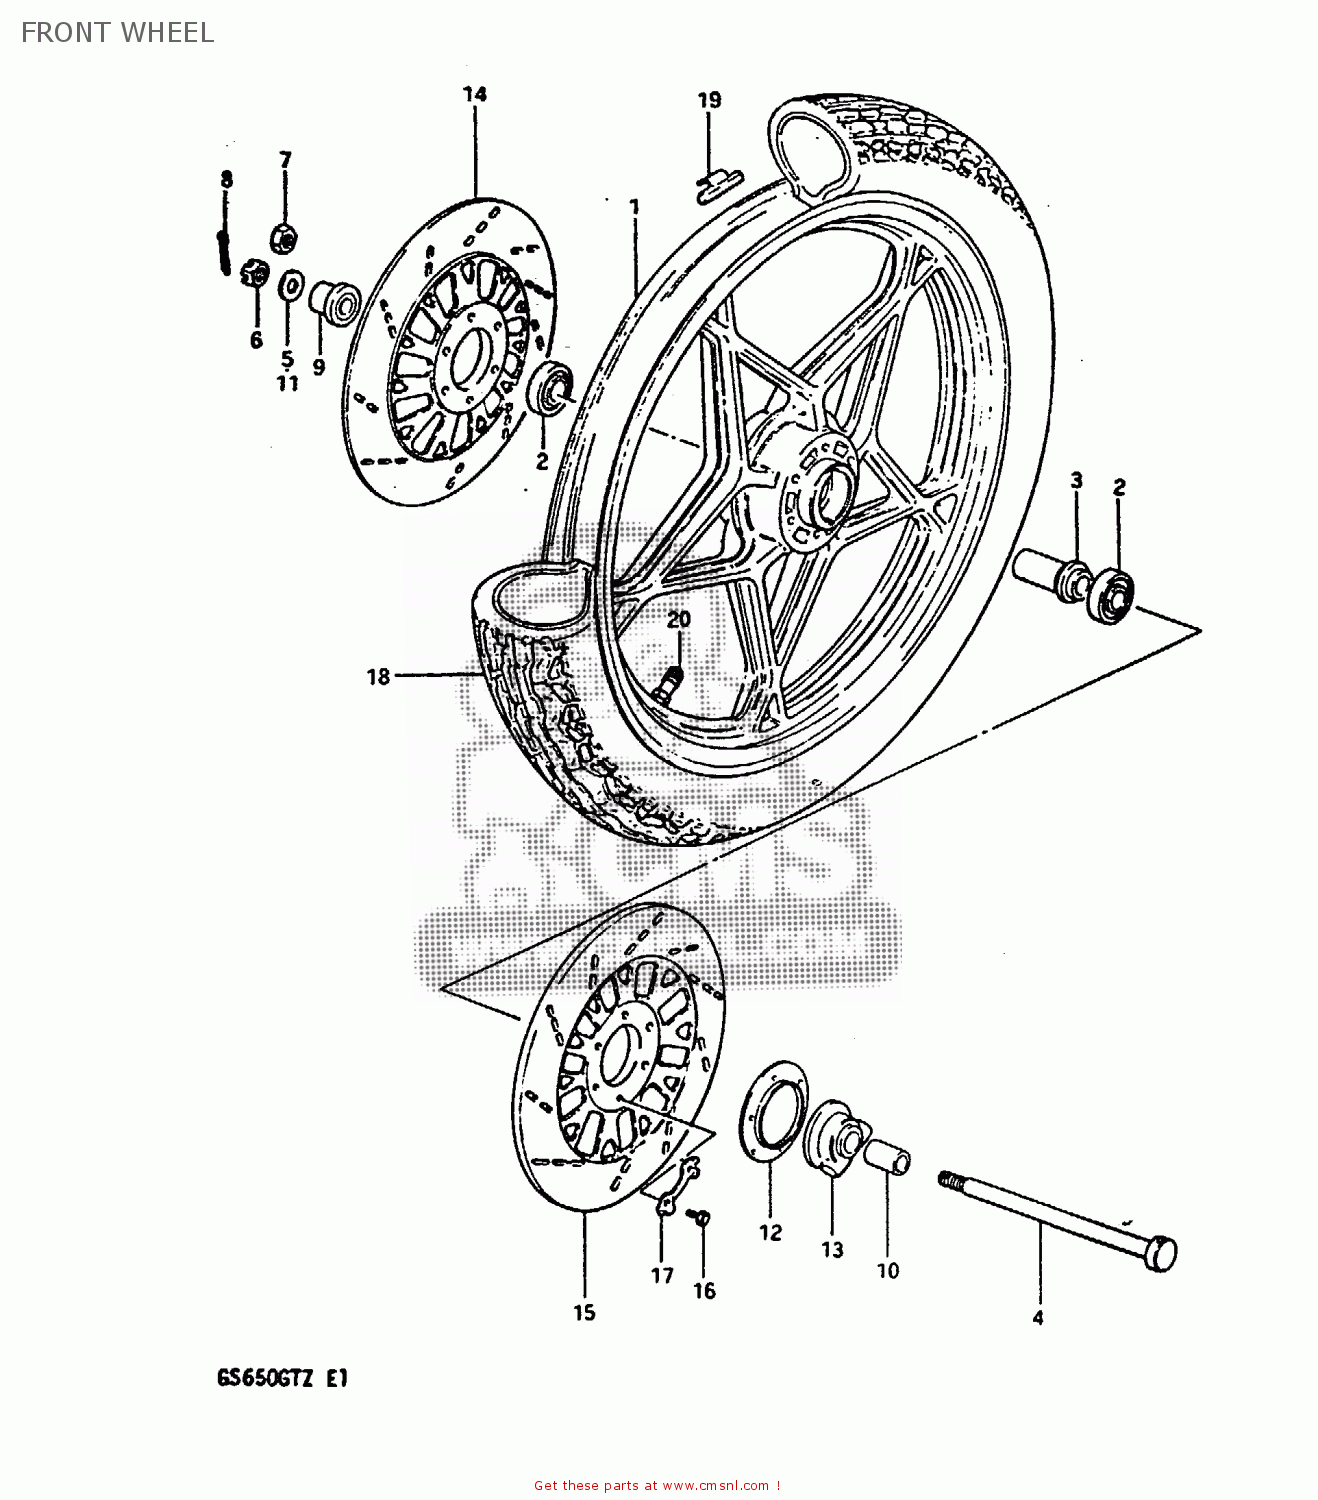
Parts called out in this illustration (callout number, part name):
1	CASTING WHEEL,FRONT 1.85
2	BEARING
3	SPACER,FR HUB BEARING
4	AXLE, FRONT
6	NUT 12MM
8	COTTER PIN
9	SPACER,FR HUB BEARING,R
10	SPACER(15X22X30)
11	WASHER
12	DUST SEAL,SPEEDOMETER GEAR BOX
13	BOX ASSEMBLY,SPEEDOMETER GEAR
14	DISC,FR BRAKE,R
15	DISC,FR BRAKE,L
16	BOLT(8X25)
17	WASHER
18	TIRE,FRONT
19	BALANCER,WHEEL
20	VALVE ASSEMBLY,WHEEL RIM,J
